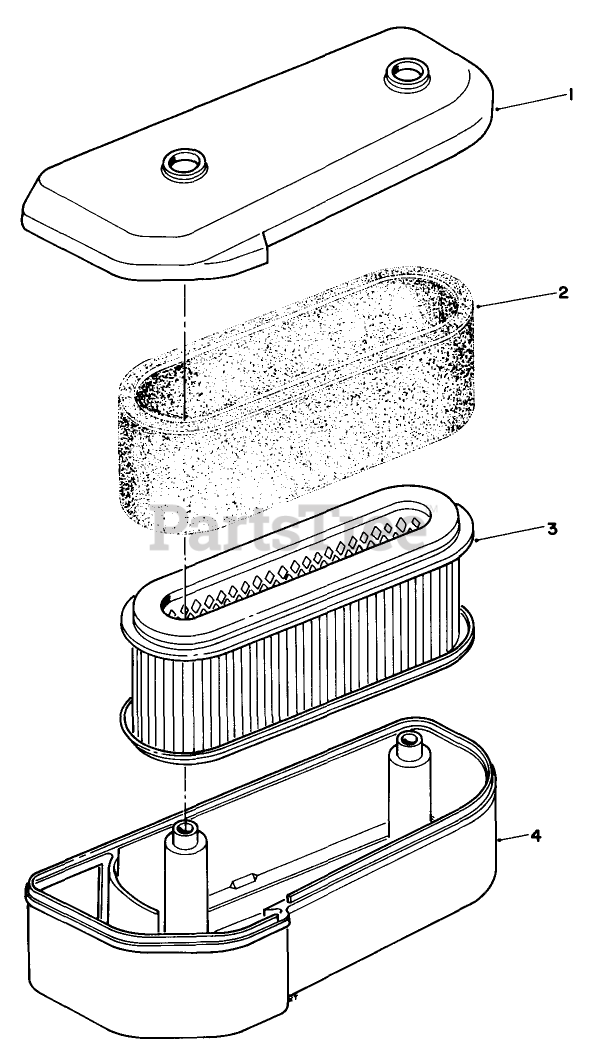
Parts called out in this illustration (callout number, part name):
1	Cap-Air Cleaner
2	Element
3	Element
4	Case-Air Cleaner
